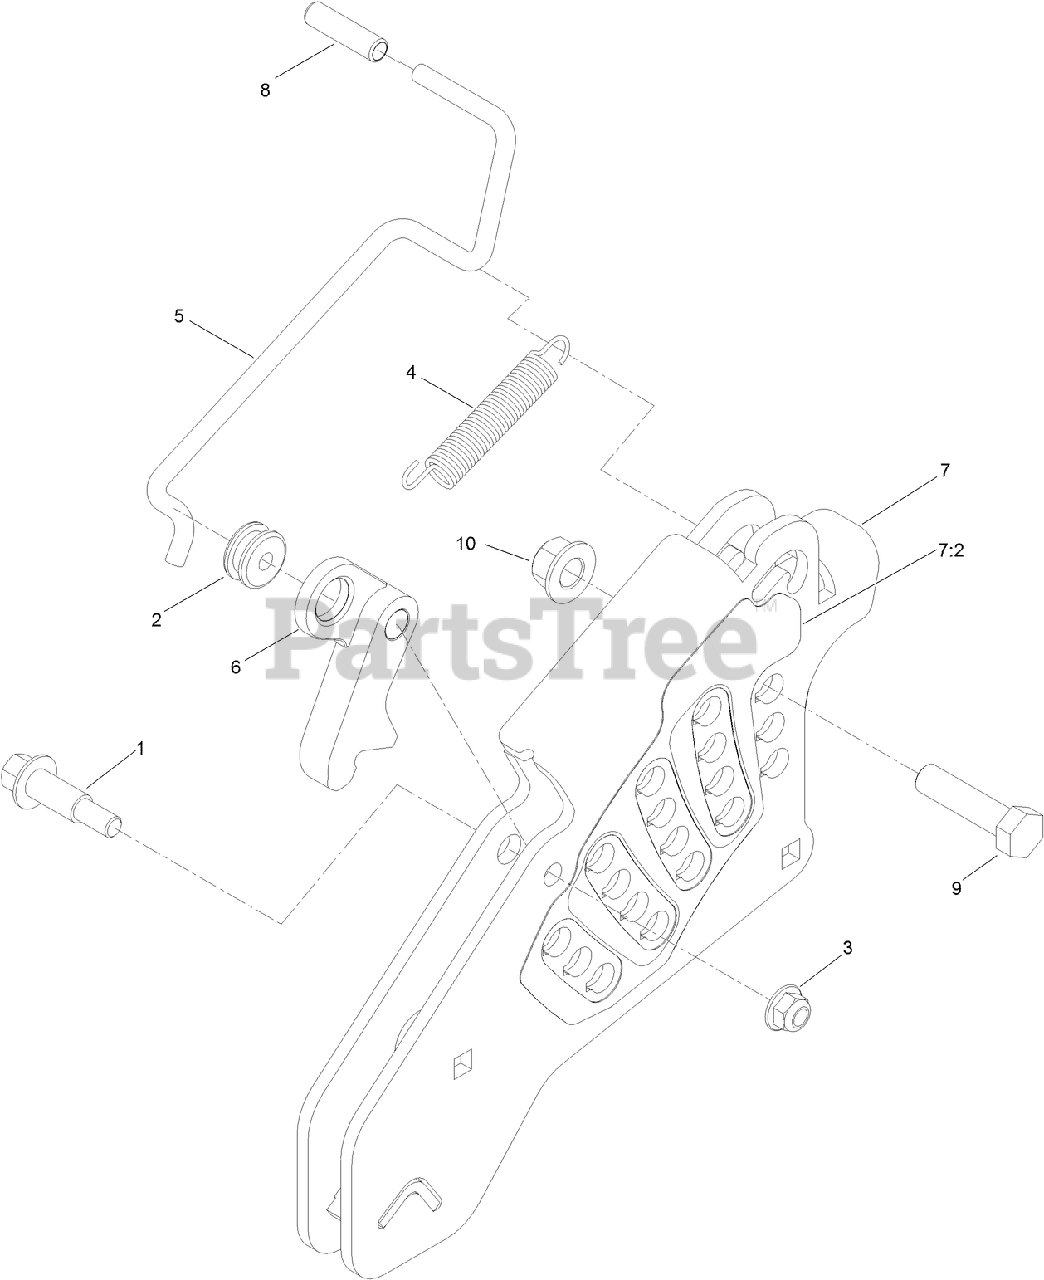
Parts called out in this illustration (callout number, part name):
1	BOLT-SHOULDER
2	GROMMET
3	NUT-HF, NI
4	SPRING-EXTENSION
5	ROD-LOCK, TRANSPORT
6	PAWL-TRANSPORT, HOC
7	HOC PLATE ASM
7:2	DECAL-HOC
8	GRIP-LEVER
9	SCREW-HH
10	NUT-LOCK
